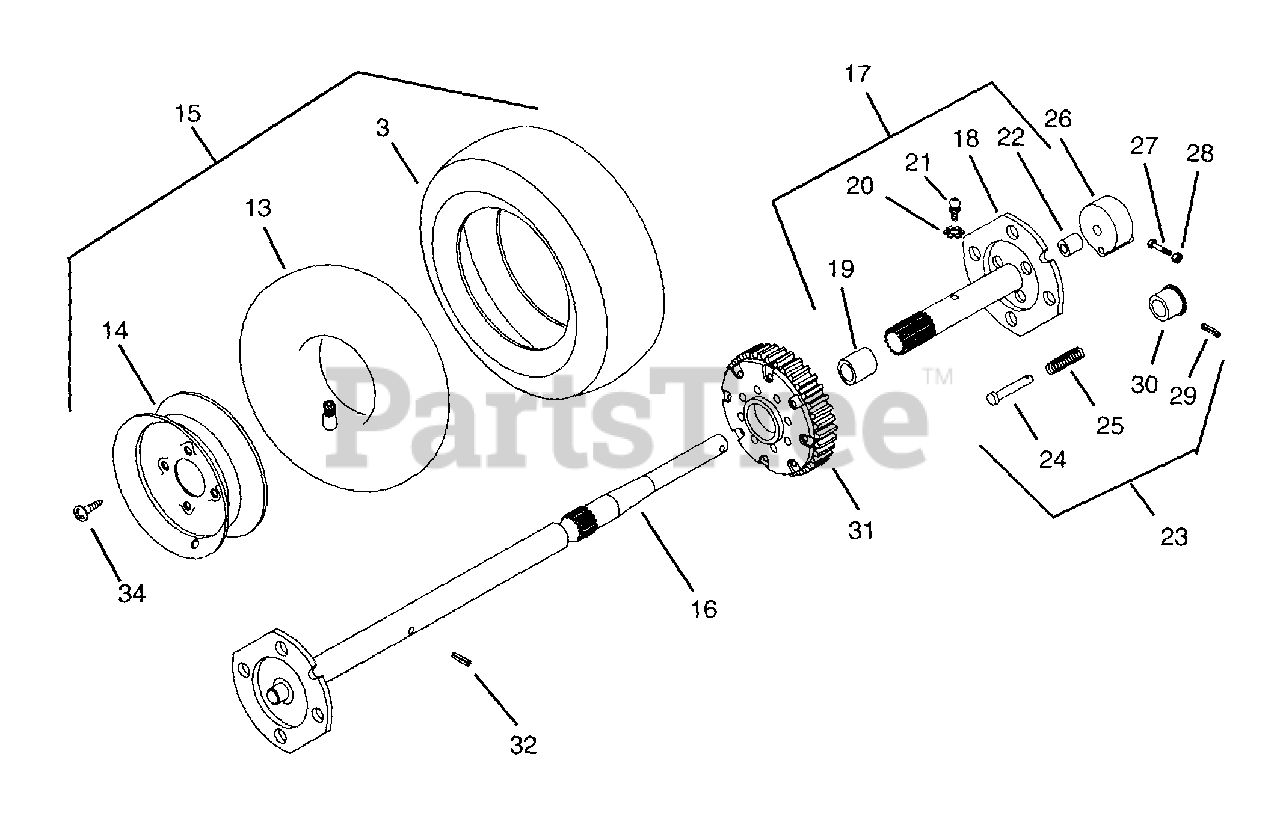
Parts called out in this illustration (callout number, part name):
3	TIRE 4.80-8 NHS
3	TIRE 16X6.50-8 SNO-HOG TREAD
13	TUBE
14	WHL
15	T/WHL ASSY 4.80-8
15	T/WHL ASSY 16X6.50-8 SNO-HOG
16	R H AXLE
17	L.H. AXLE ASSEMBLY
17	L.H.AXLE ASSEMBLY
18	AXLE, LH
19	BSHG-SLV .750X.814X .750 BRZ
20	WSHR-LK .250X.047 LT YWZC
21	FTG-LUBE .25-28X.256 YWZC
22	BSHG-SLV .562X.625X.625 BRZ
23	LOCKOUT HUB ASSEMBLY
24	PIN
25	SG-COMP .028X.34X1.062 WLD75
26	LOCKOUT HUB
27	BLT-HEX .25-20X2.0 PL GR8 YWZC
28	NUT-JAM-NYL .250-20 W/INSERTYZ
29	PIN-ROLL .093X1.00
30	KNOB
31	DIFFERENTIAL ASSEMBLY
32	PIN-ROLL .188X1.50
34	SCR-TAP .500-20X.62 HH YWZC
